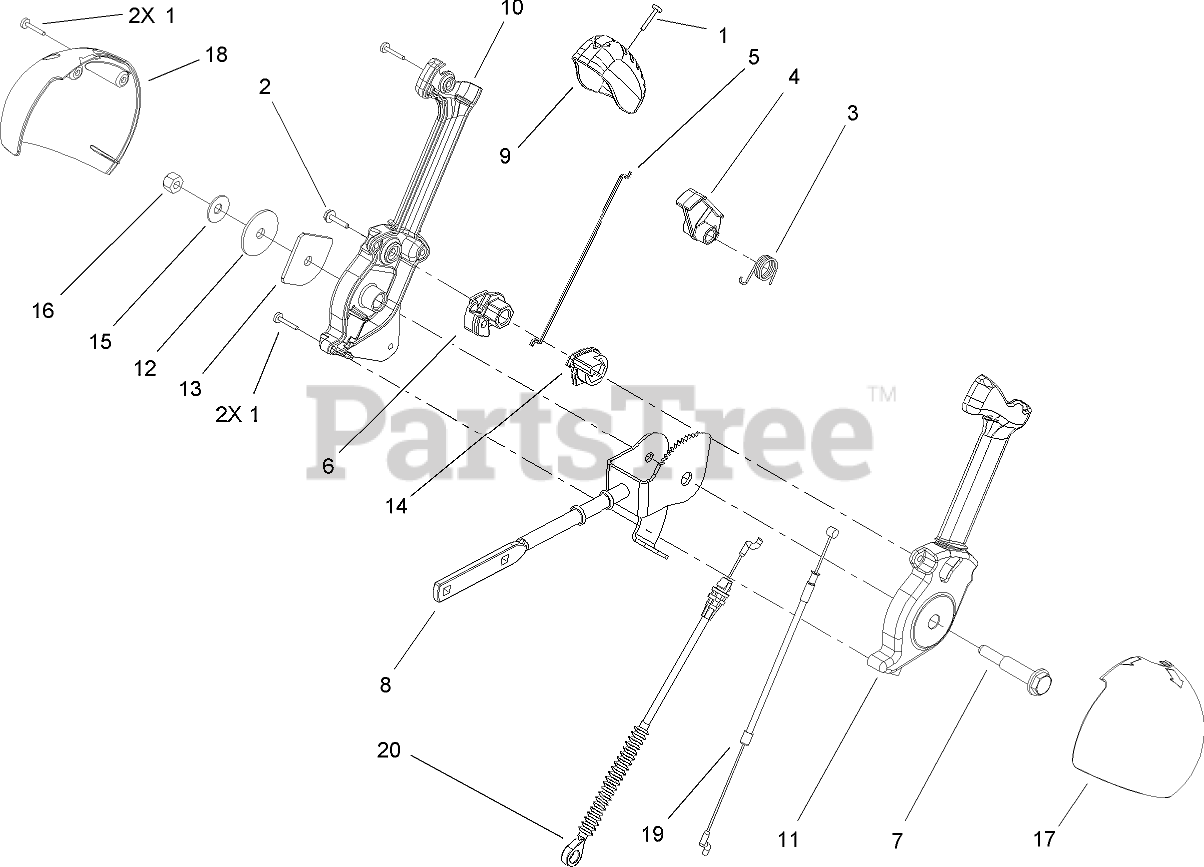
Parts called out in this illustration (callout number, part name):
1	SCREW-PPH
2	SCREW-HWH
3	SPRING-TORSION
4	TRIGGER-LATCH
5	LINK-LATCH
6	LEVER-CABLE, DEFLECTOR
7	SCREW-SHOULDER
8	ROD-CONTROL, CHUTE
9	CAP-LEVER
10	LEVER-CONTROL, CHUTE (RH)
11	LEVER-CONTROL, CHUTE (LH)
12	WASHER-NYLON
13	PLATE-FRICTION
14	PAWL-LATCH
15	WASHER-BELLEVILLE
16	NUT-LOCK, NI
17	COVER-LEVER, CHUTE (LH)
18	COVER-LEVER, CHUTE (RH)
19	CABLE-RELEASE, CHUTE
20	CABLE-CONTROL, DEFLECTOR
